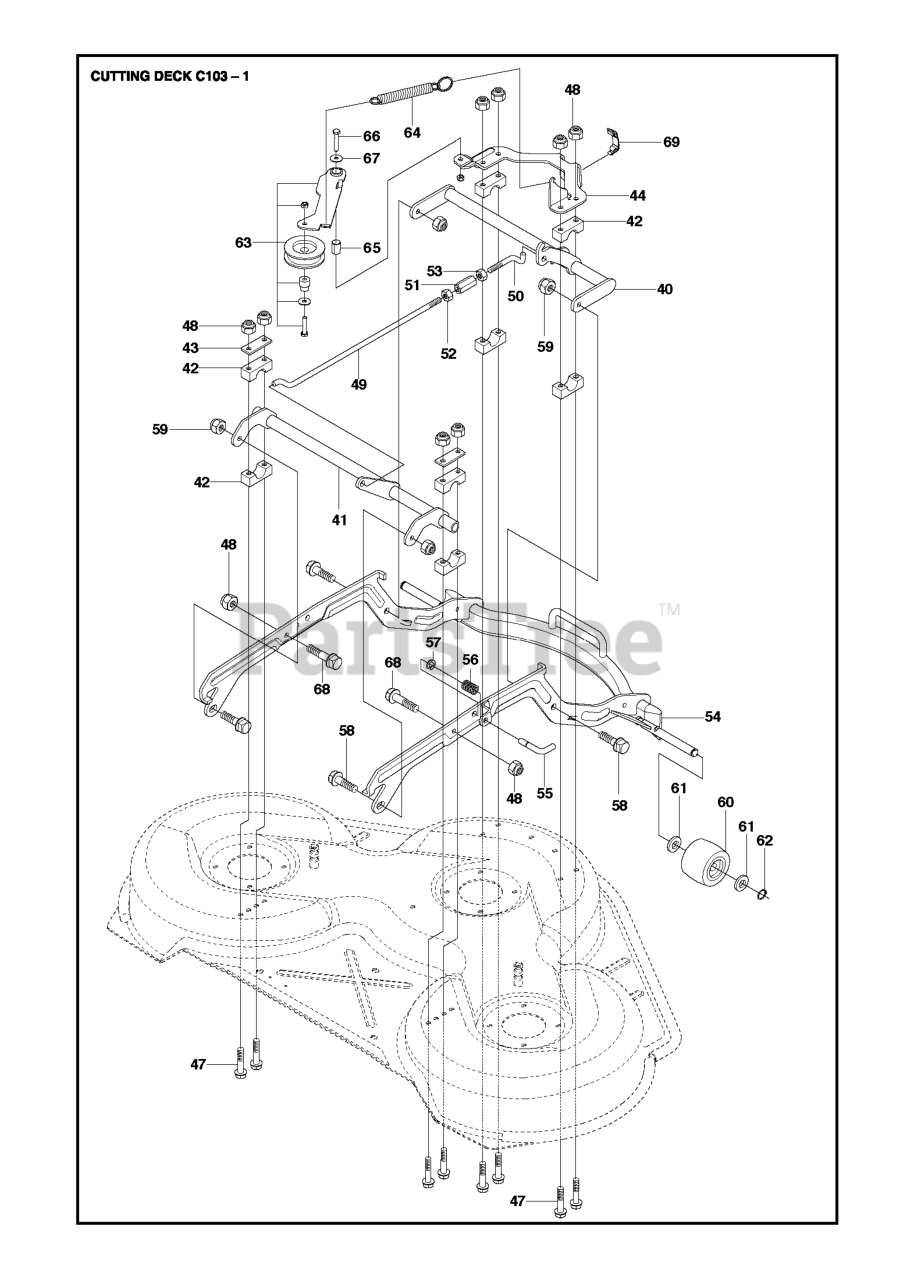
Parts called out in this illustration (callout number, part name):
48	LOCKNUT M8
53	NUT
59	LOCKNUT M8
60	DECK ROLLER, FRONT
62	RETAINING RING SGA 15
66	SCREW
68	COLLAR SCREW
69	CLIP GRAY
